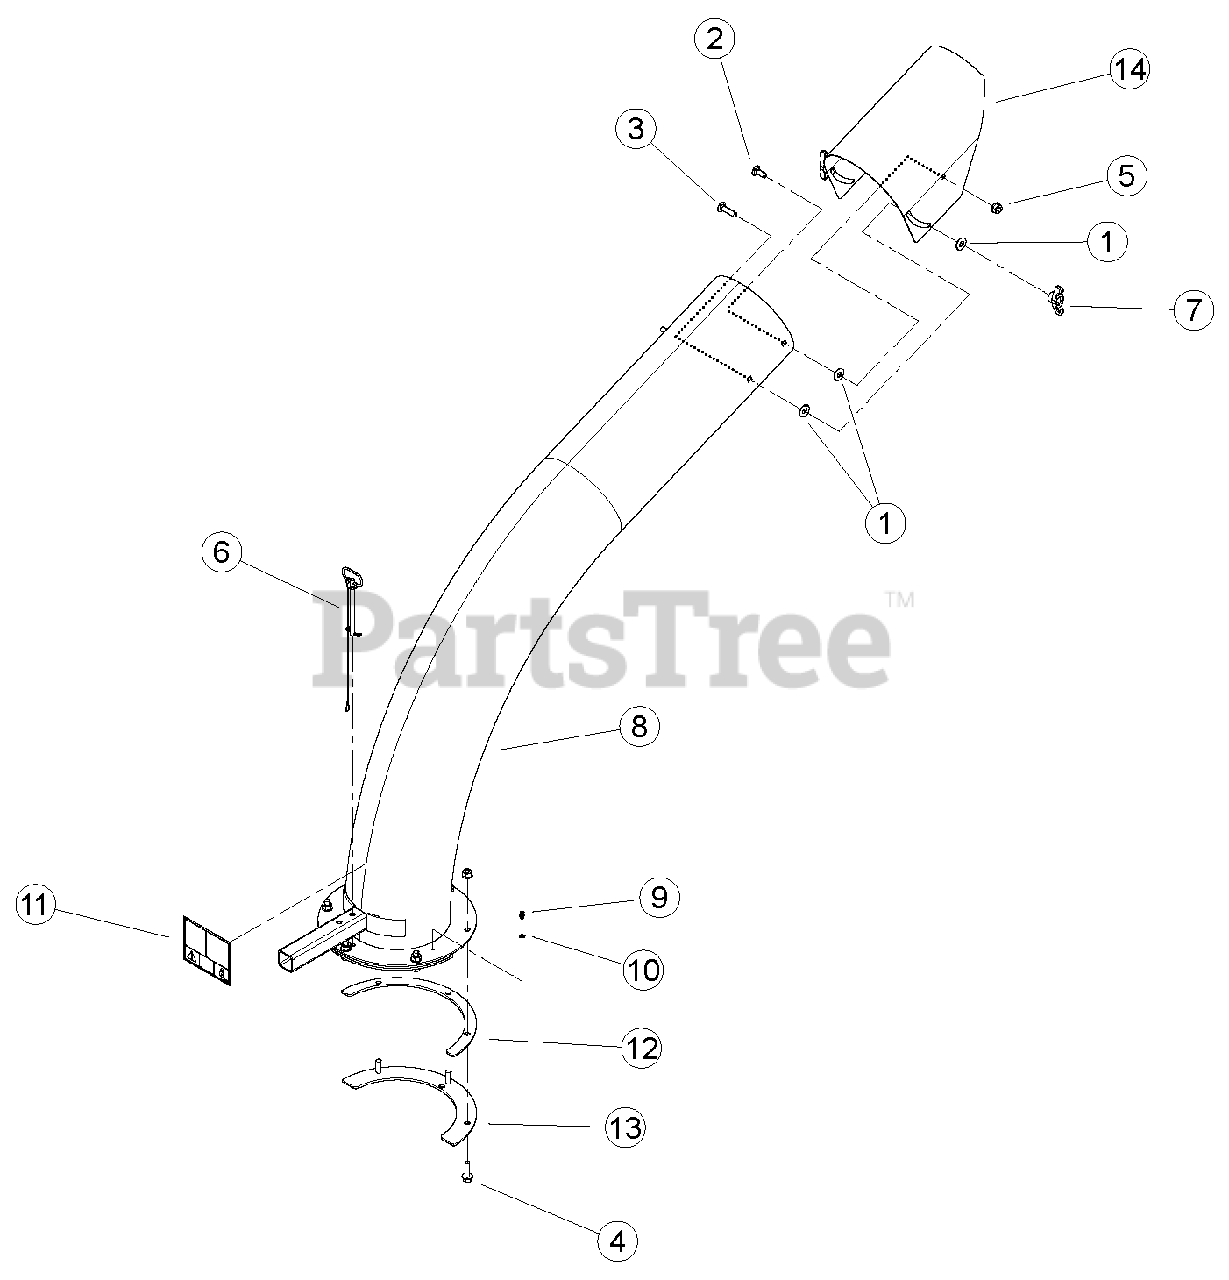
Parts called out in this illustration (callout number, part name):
1	WASHER, 3/8" FLAT ZP
2	BOLT, 3/8 X 1" GR5 CRG NC ZP
3	BOLT, 3/8 X 1-1/2" GR5 NC ZP
4	BOLT, 3/8 X 1-1/4 FLANGE NC
5	NUT, 3/8-16 NYLOCK FLANGE
6	PIN, 3/8 X 4.25" DISCHARGE
7	KNOB, 3/8-16 UNC FEMALE TEE
8	ASSEMBLY, 8 INCH DISCHARGE CHUTE
9	FITTING, 1/4 SELF-TAP GREASE
10	WASHER, FLAT .254 X .400 X .048
11	DECAL, DISCHARGE DEBRIS & LOCK
12	RING, DISCHARGE SPACER
13	RING, DISCHARGE CLAMP
14	CAP, 8 INCH DISCHARGE CHUTE
